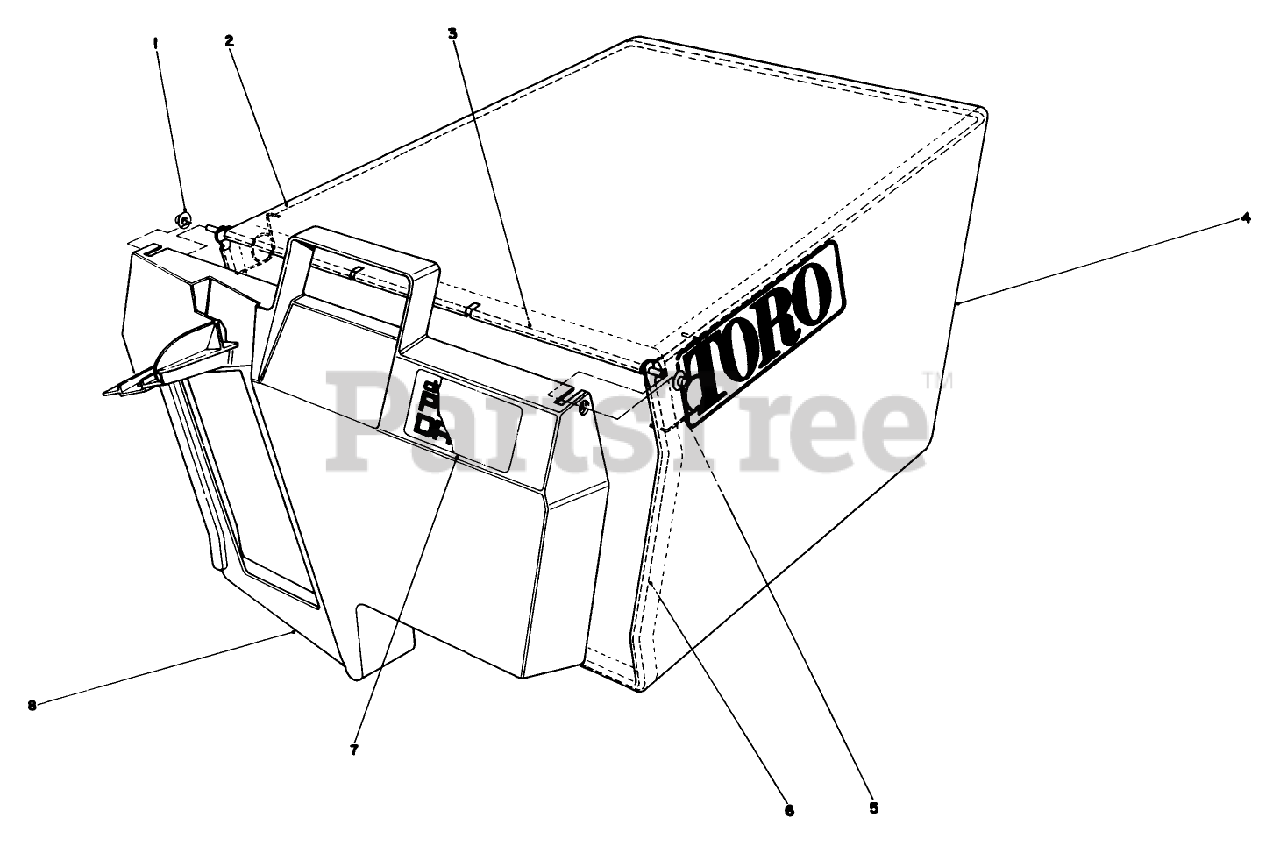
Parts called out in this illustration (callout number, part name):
1	NUT-PUSH
3	HINGE-DOOR, BAG
4	BAG-GRASS
5	SPRING
6	FRAME-BAG
7	BAG DOOR DECAL
8	DOOR-BAG
